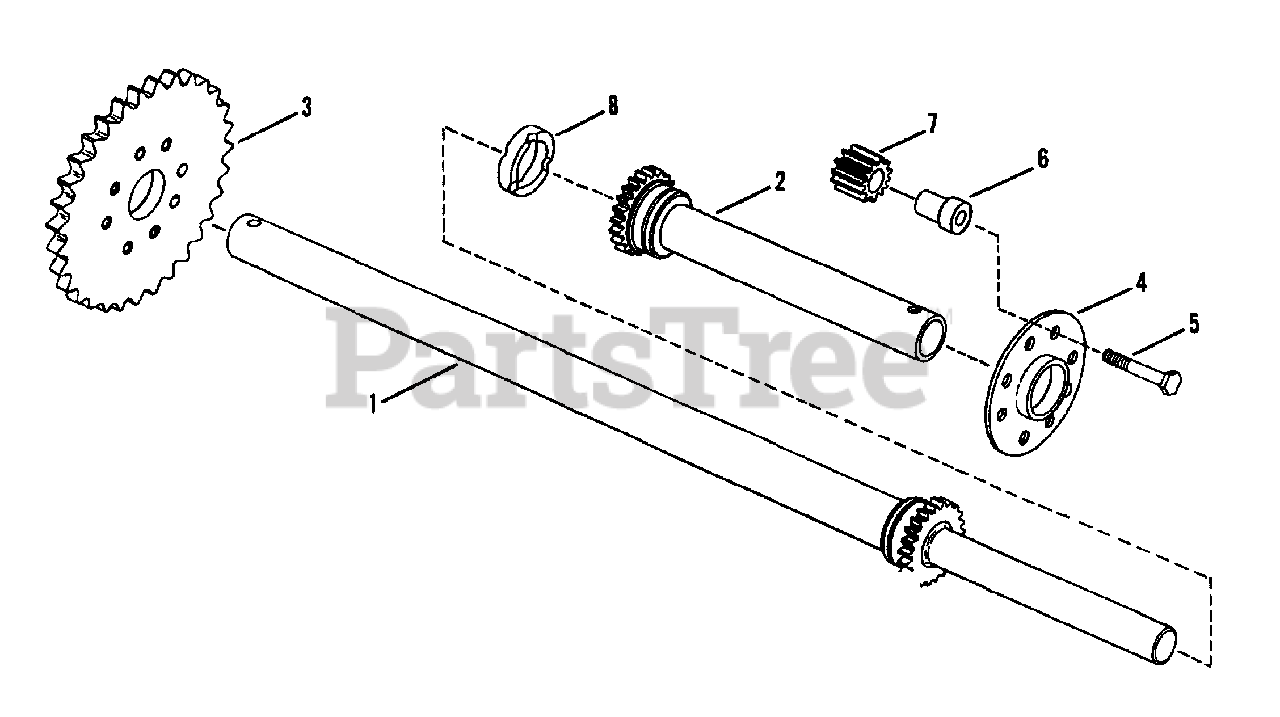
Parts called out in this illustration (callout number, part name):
1	AXLE, Long
2	AXLE, Short
3	SPROCKET, 31 Tooth
4	PLATE, Differential
5	SCREW, 5/16-24 x 1-5/8" Hex Head Cap (Special) Lock, Grade 5
6	SPACER, Pinion
7	PINION GEAR, Differential
8	SPACER, Differential (1.25" ID x .425 Wide)
